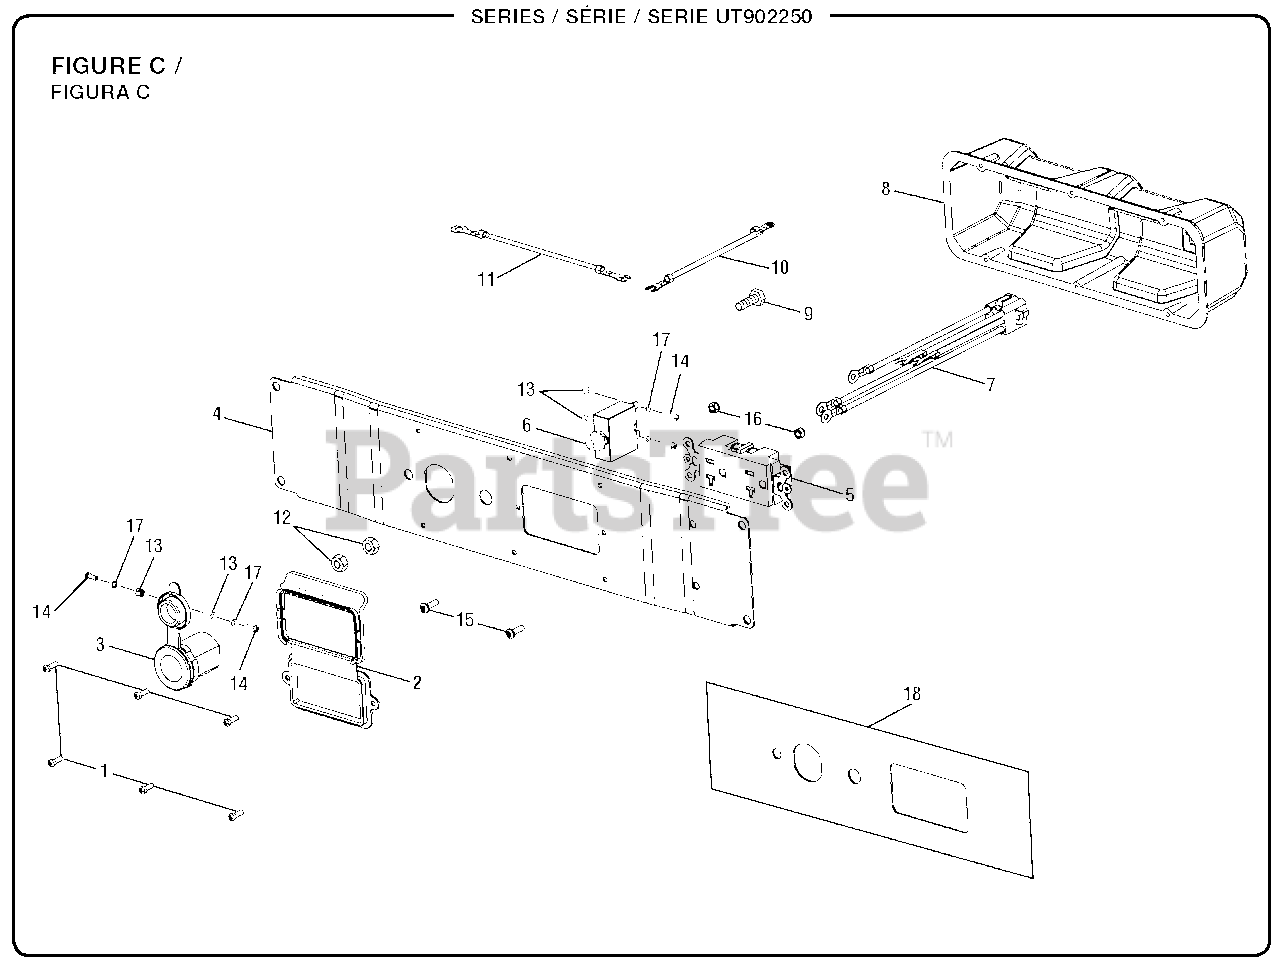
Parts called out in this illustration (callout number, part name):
1	Screw (6-20 x 3/8 in., Pan Hd.)
2	Outlet Cover (120 Volt)
3	DC Voltage Outlet
4	Front Panel
5	120 Volt Receptacle
6	Circuit Breaker (20 Amp, 125 Volt)
7	Socket Connector Assembly (9 Pin)
8	Back Panel
9	Bolt (1/4-20 x 5/8 in., Hex Hd.)
10	Black Lead Assembly
11	Ground Wire Assembly
12	Hex Nut (1/4-20)
13	Lock Nut (M3)
14	Bolt (M3 x 8 mm)
15	Bolt (M4 x 12 mm, Button Hd.)
16	Flange Nut (M4 x 0.7)
17	Lock Washer
18	Power Outlet Panel Label.
